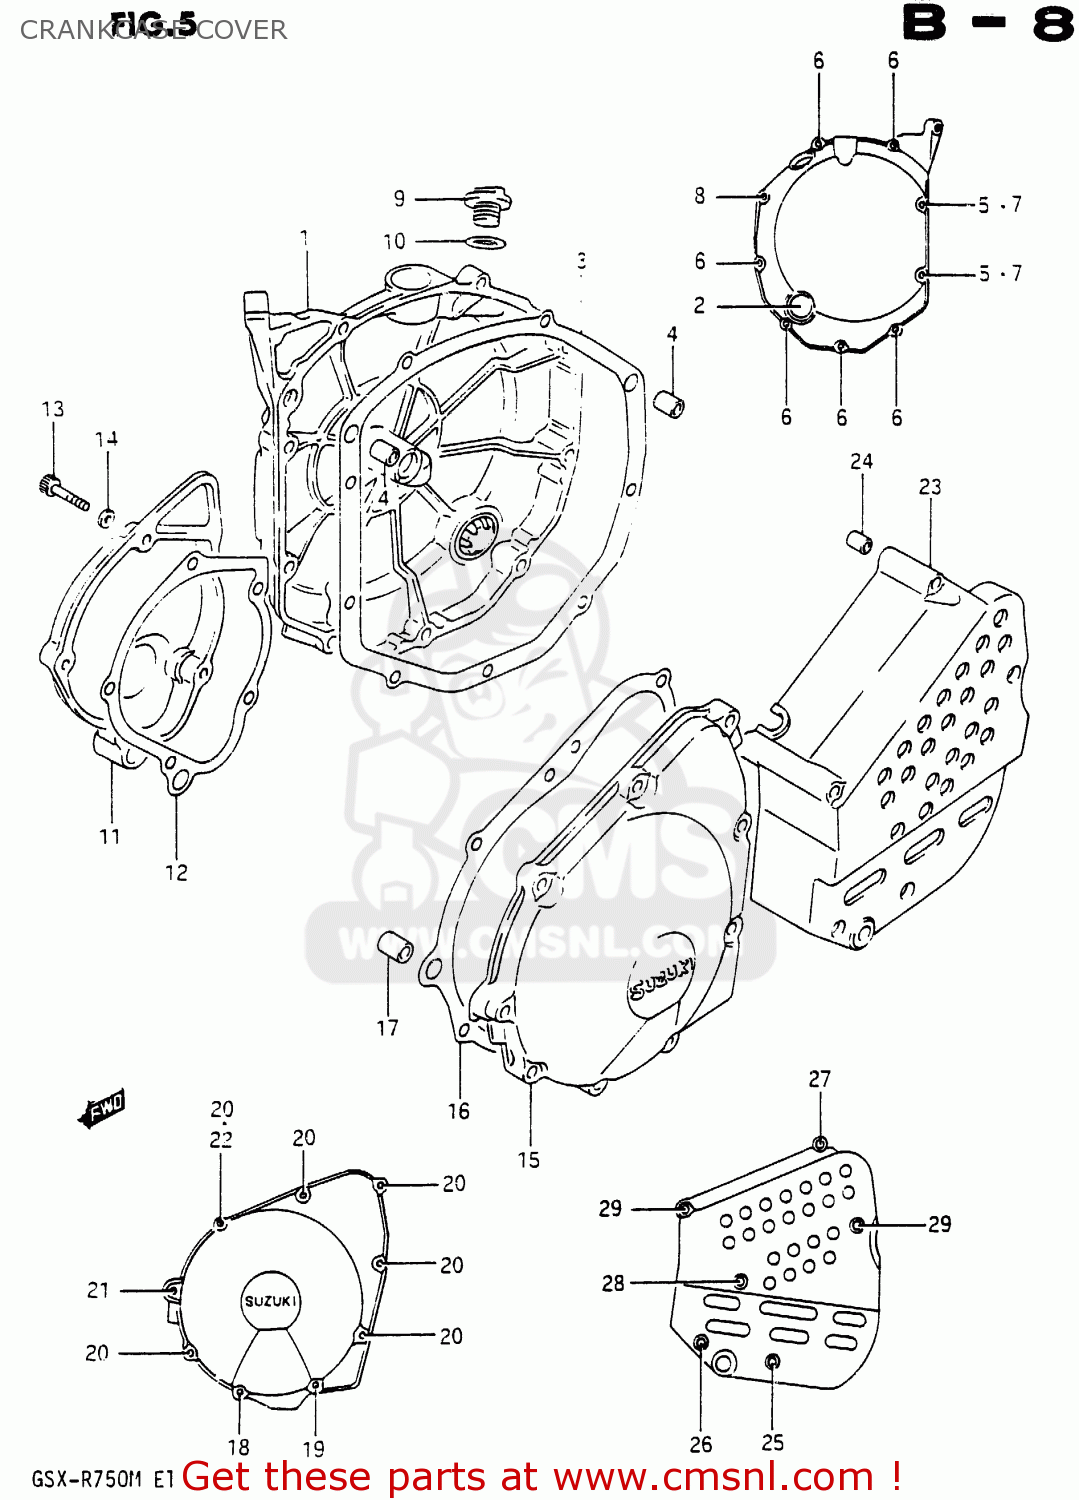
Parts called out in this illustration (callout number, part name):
1	COVER,CLUTCH
2	LENS,OIL LEVEL CHECK
3	GASKET,CLUTCH COVER (NAS)
4	PIN
5	GASKET(5.8X11X1.2) (NAS)
6	BOLT
7	BOLT
8	BOLT
9	PLUG
10	O RING(D:3.1,ID:16.8)
11	COVER,SIGNAL GENERATOR
12	GASKET,SIGNAL GENERATOR COVER (NAS)
13	BOLT
14	GASKET(5.8X11X1.2) (NAS)
15	COVER,STARTER GEAR
16	GASKET,STARTER GEAR COVER (NAS)
17	PIN (11X20)(SUS)
18	BOLT
19	BOLT
20	BOLT
21	BOLT
22	GASKET(5.8X11X1.2) (NAS)
23	COVER,ENGINE SPROCKET
24	PIN
25	BOLT
26	BOLT
27	BOLT
28	BOLT
29	BOLT
